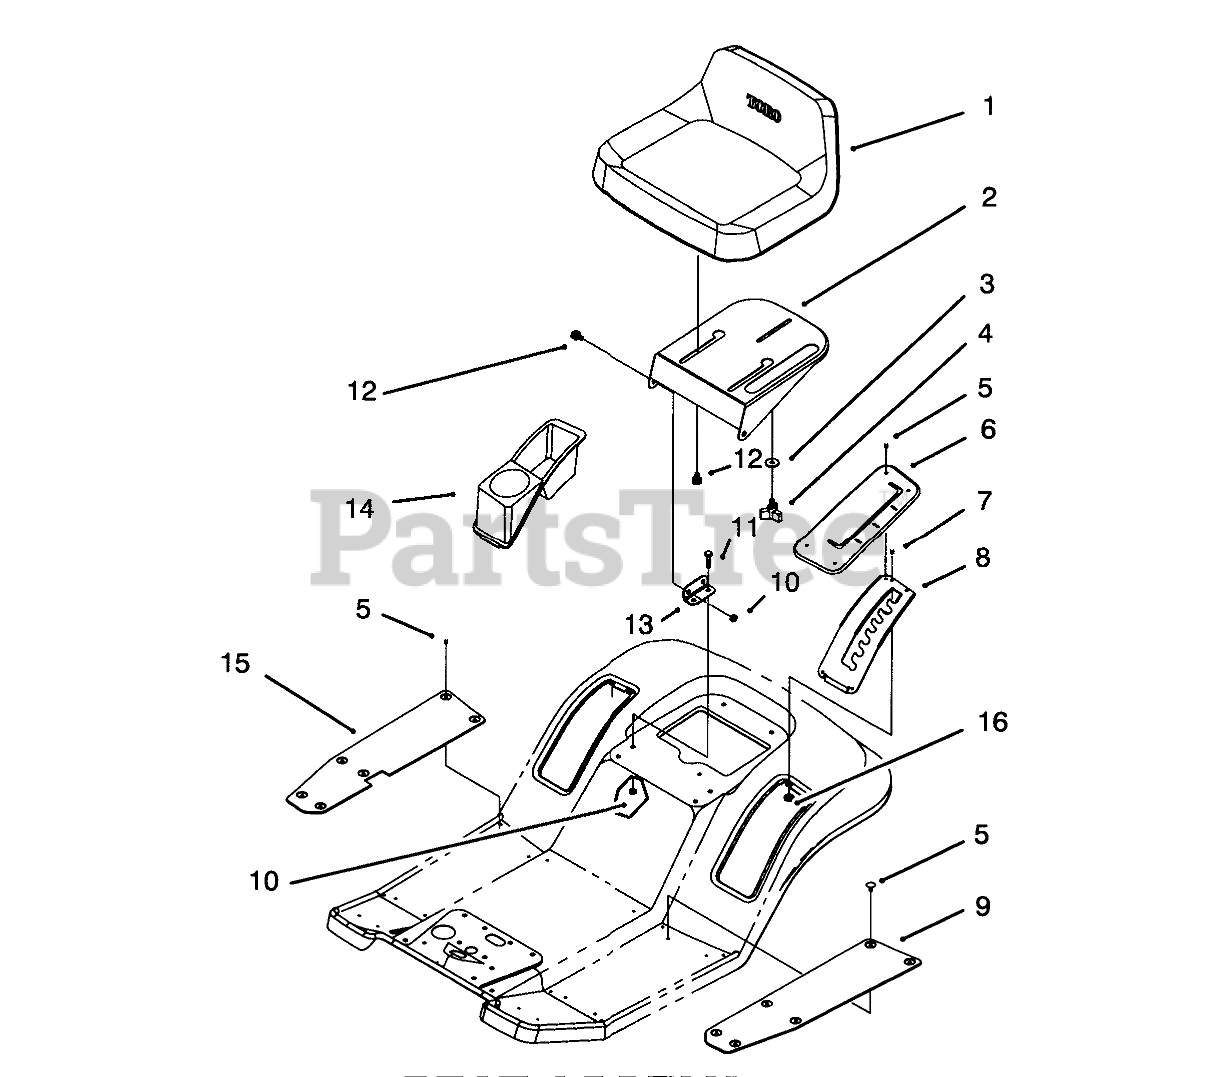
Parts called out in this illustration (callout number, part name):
1	SEAT
2	Support-Seat
3	WASHER-PIVOT
5	FASTENER-PANEL
6	COVER-HOC
7	RIVET-POP
8	Gate-H.O.C.
9	MAT-FOOT, LH
10	NUT-LOCK, NI
11	SCREW-HH
12	BOLT-SHOULDER
13	Bracket-Seat Hinge
14	TRAY-FENDER
15	MAT-FOOT, RH
16	WASHER-FLAT
